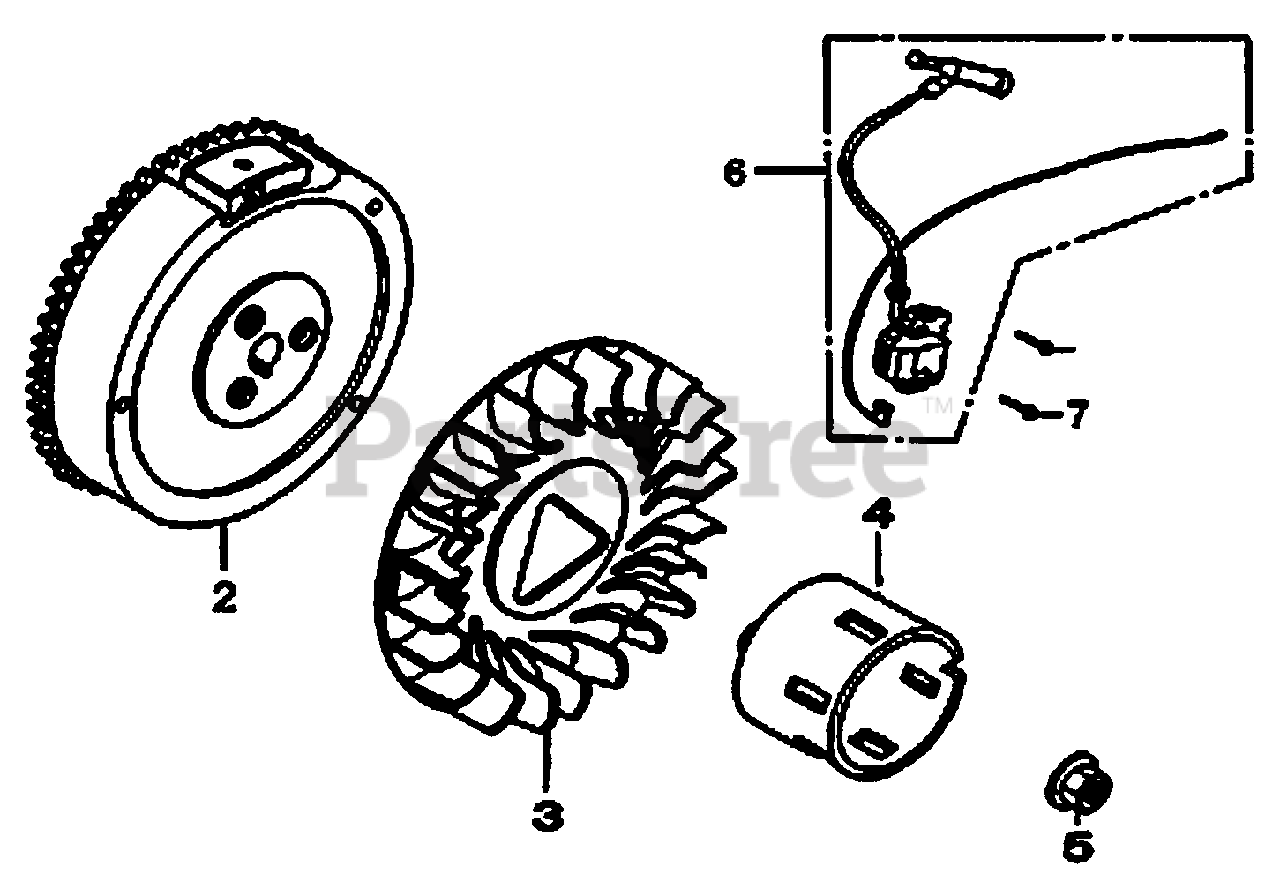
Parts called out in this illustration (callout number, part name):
2	FLYWHEEL COMP.
3	FAN COOLING
4	PULLEY, STARTER
5	NUT SPECIAL, M16
6	COIL ASSY., IGNITION
7	BOLT, FLANGE, M6X25
